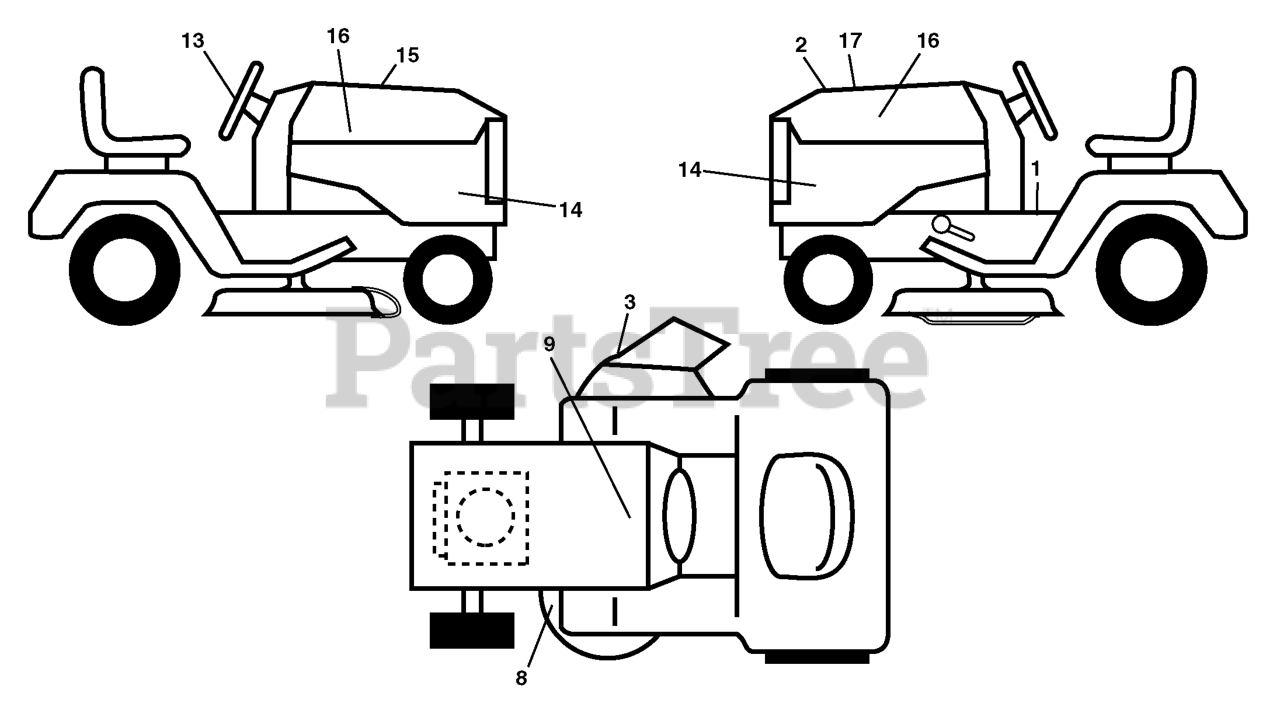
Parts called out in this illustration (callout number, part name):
1	DECAL.FENDER.OPER.TEX.
2	DECAL.HOOD.TOP.INSERT.
3	DECAL.WARN.KEEP.HAND.AWAY
8	DECAL V BELT SCHEMATIC
9	DECAL BTRY SYMBOLS
13	DECAL.WHEEL.STRG.LGN.H
14	DECAL.PANEL.SIDE.YTH20F42T
15	DECAL HOOD CUST. RESP.
16	DECAL.HOOD.LOGO.PLAQUE
17	DECAL.RPL.KH.20.TGB.42
